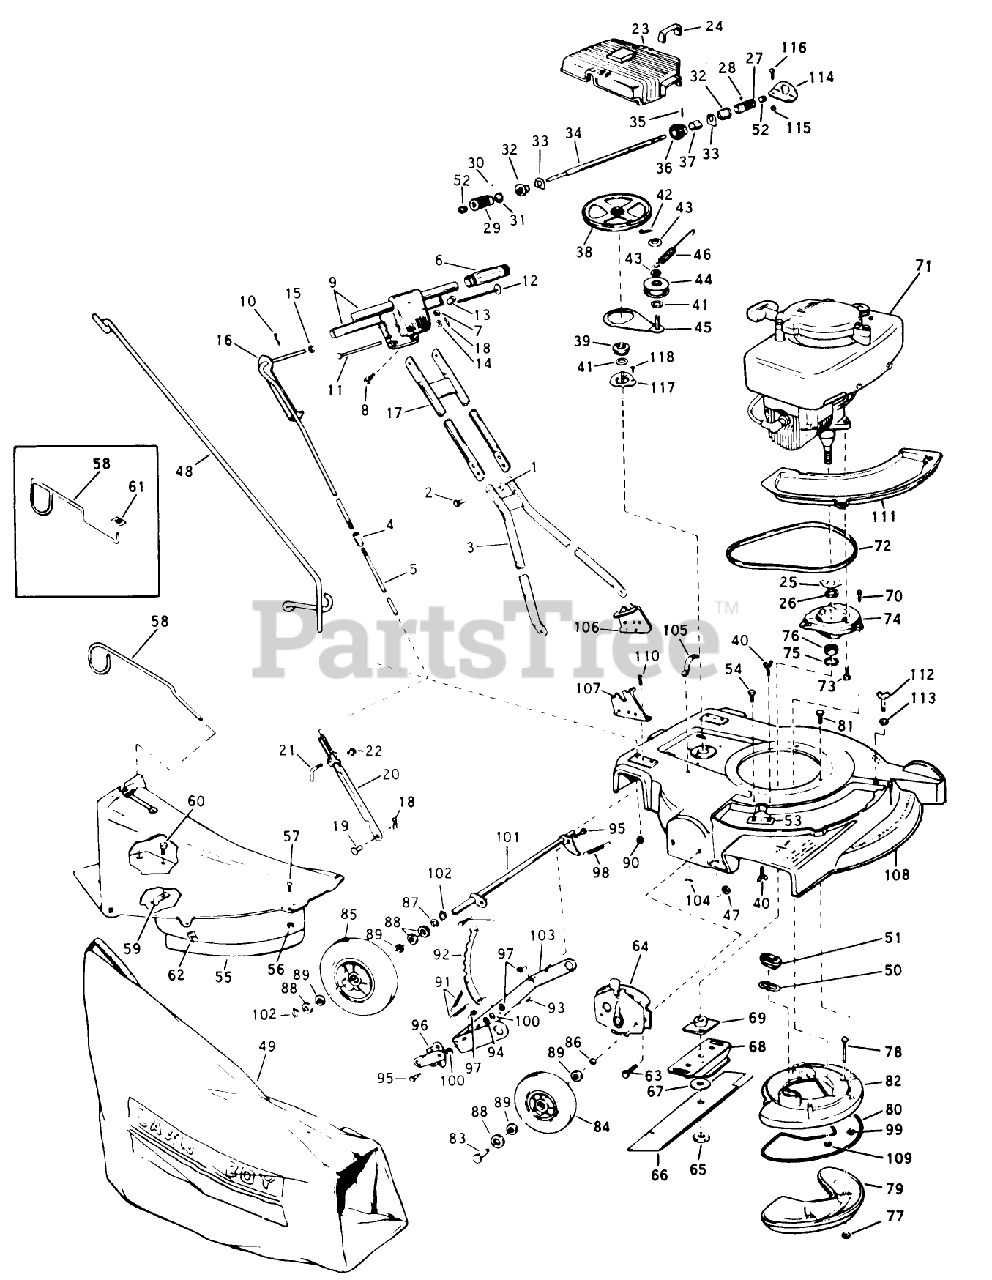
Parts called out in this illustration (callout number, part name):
10	Pin-Cotter
38	PULLEY&OILER FELT (13)
49	89802 LB WHOLE GOODS
50	GASKET S
52	GREASE PLUG
55	Chute Skirt Assembly (Includes Hardware)
62	SPEED NUT ARDEN
65	NUT-BLADE
69	PLATE AND COLLAR ASM
77	LOCKNUT E
83	BOLT WHEEL
86	WASHER WROUGHT
95	BOLT RB&W
97	STOP NUT
100	WASHER S
102	RETAINING RING
110	SCREW S
